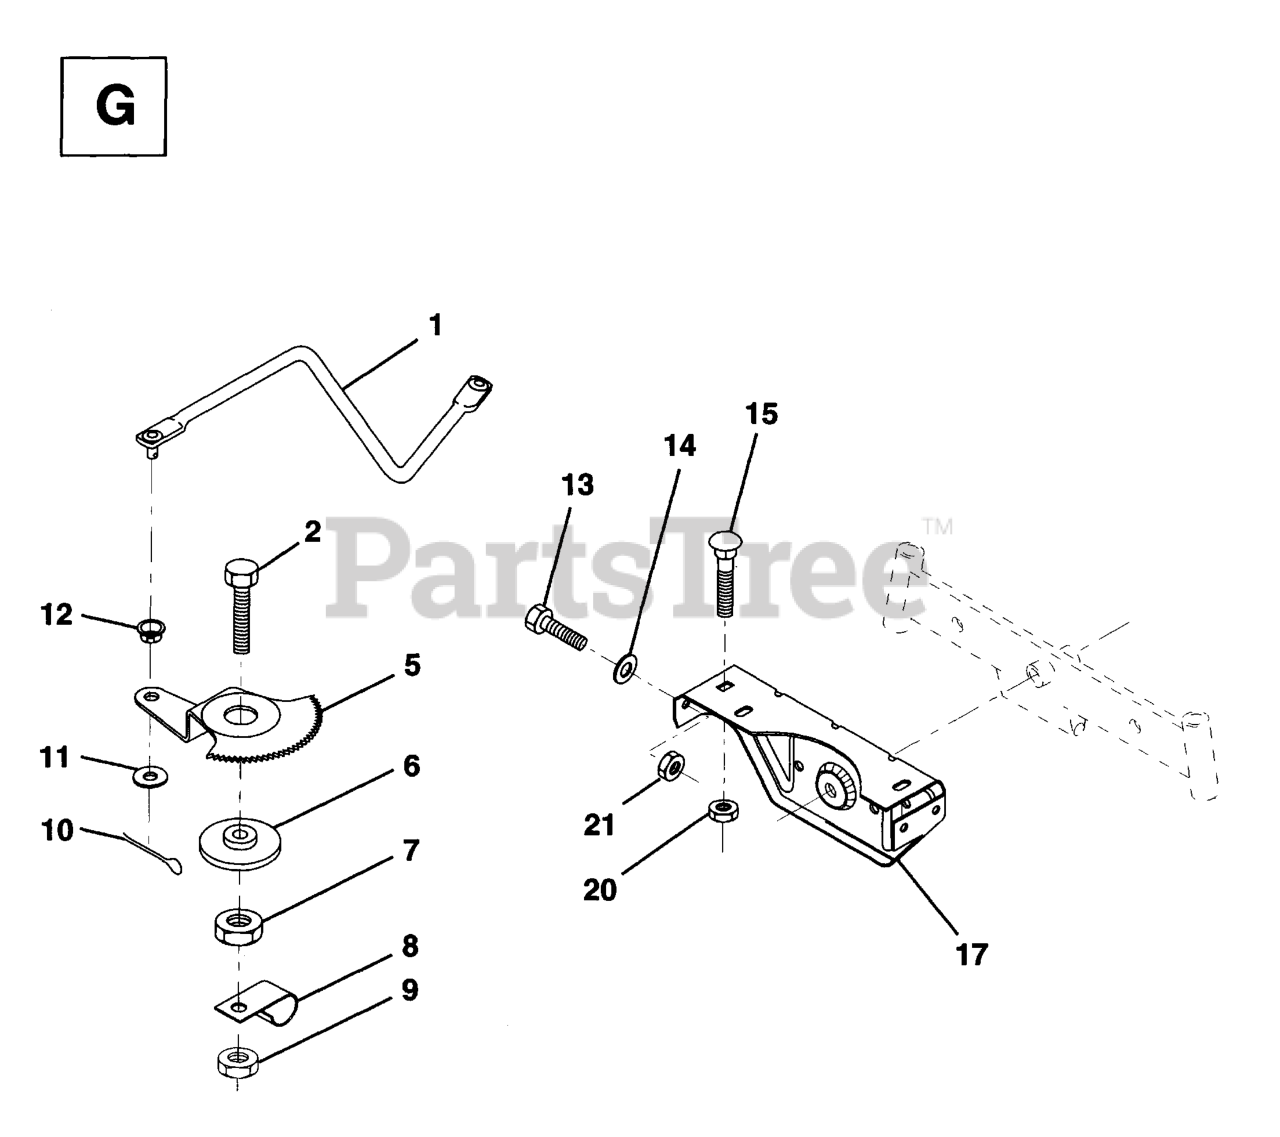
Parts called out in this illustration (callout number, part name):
5	GEAR SECTOR
7	NUT
8	CLIP INSULATOR
9	NUT LTV
10	COTTER PIN
11	WASHER
12	BUSHING.DRAGLINK (2 2)
13	BOLT
14	WASHER
15	BOLT
17	SUPPORT/AXLE FRONT
21	LOCKNUT
